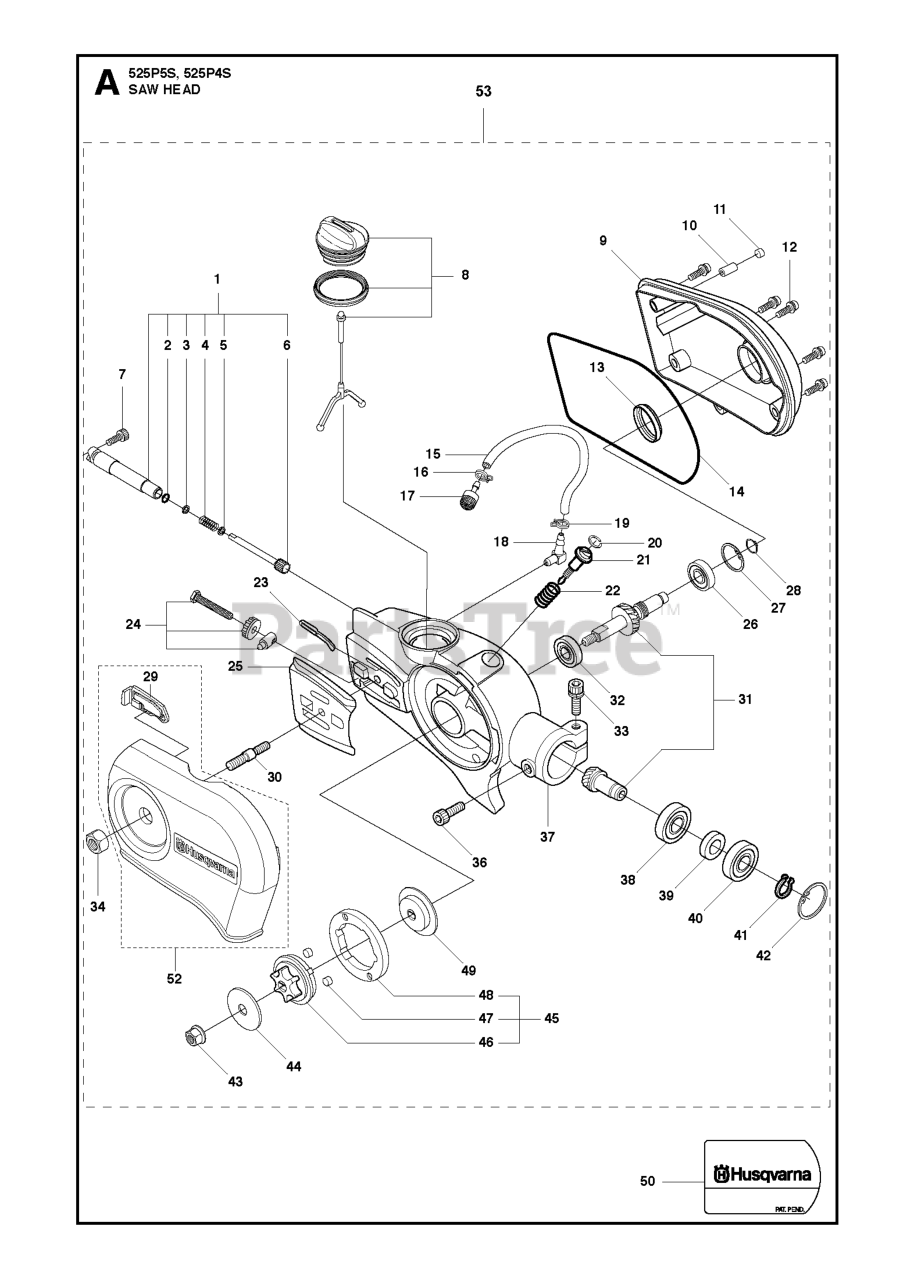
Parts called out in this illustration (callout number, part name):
1	OIL PUMP
2	O-RING
3	WASHER 5.1X8.5
4	SPRING
5	WASHER 5.1X8.5
6	%PUMP PISTON
7	SCREW MC6S 5X12
8	OIL TANK CAP GREY
9	COVER
10	VALVE
11	PLUG
12	SCREW MC6S 5X16
13	RING
14	O-RING
15	HOSE
16	CLIP
17	OIL PLUMMET
18	NIPPLE
19	CLIP
20	RETAINING RING
21	SCREW
22	SPRING
23	SEALING
24	CHAIN TENSIONER
25	PLATE
26	BALL BEARING
27	RETAINING RING SGH 26
28	RETAINING RING SGA 10
29	SEALING PLATE
30	BAR BOLT
31	GEAR
32	BALL BEARING
33	SCREW MC6S 5X25
34	NUT
36	SCREW MC6S 5X12
37	HOUSING
38	BALL BEARING
39	SPACER SLEEVE
40	BALL BEARING
41	RETAINING RING
42	RETAINING RING
43	FLANGE NUT
44	FENDER WASHER
45	SPROCKET KIT
46	SPROCKET
47	VIBRATION ABSORBER
48	FLYWHEEL
49	COVER
52	CHAIN GUARD
53	CUTTING HEAD ASSY
